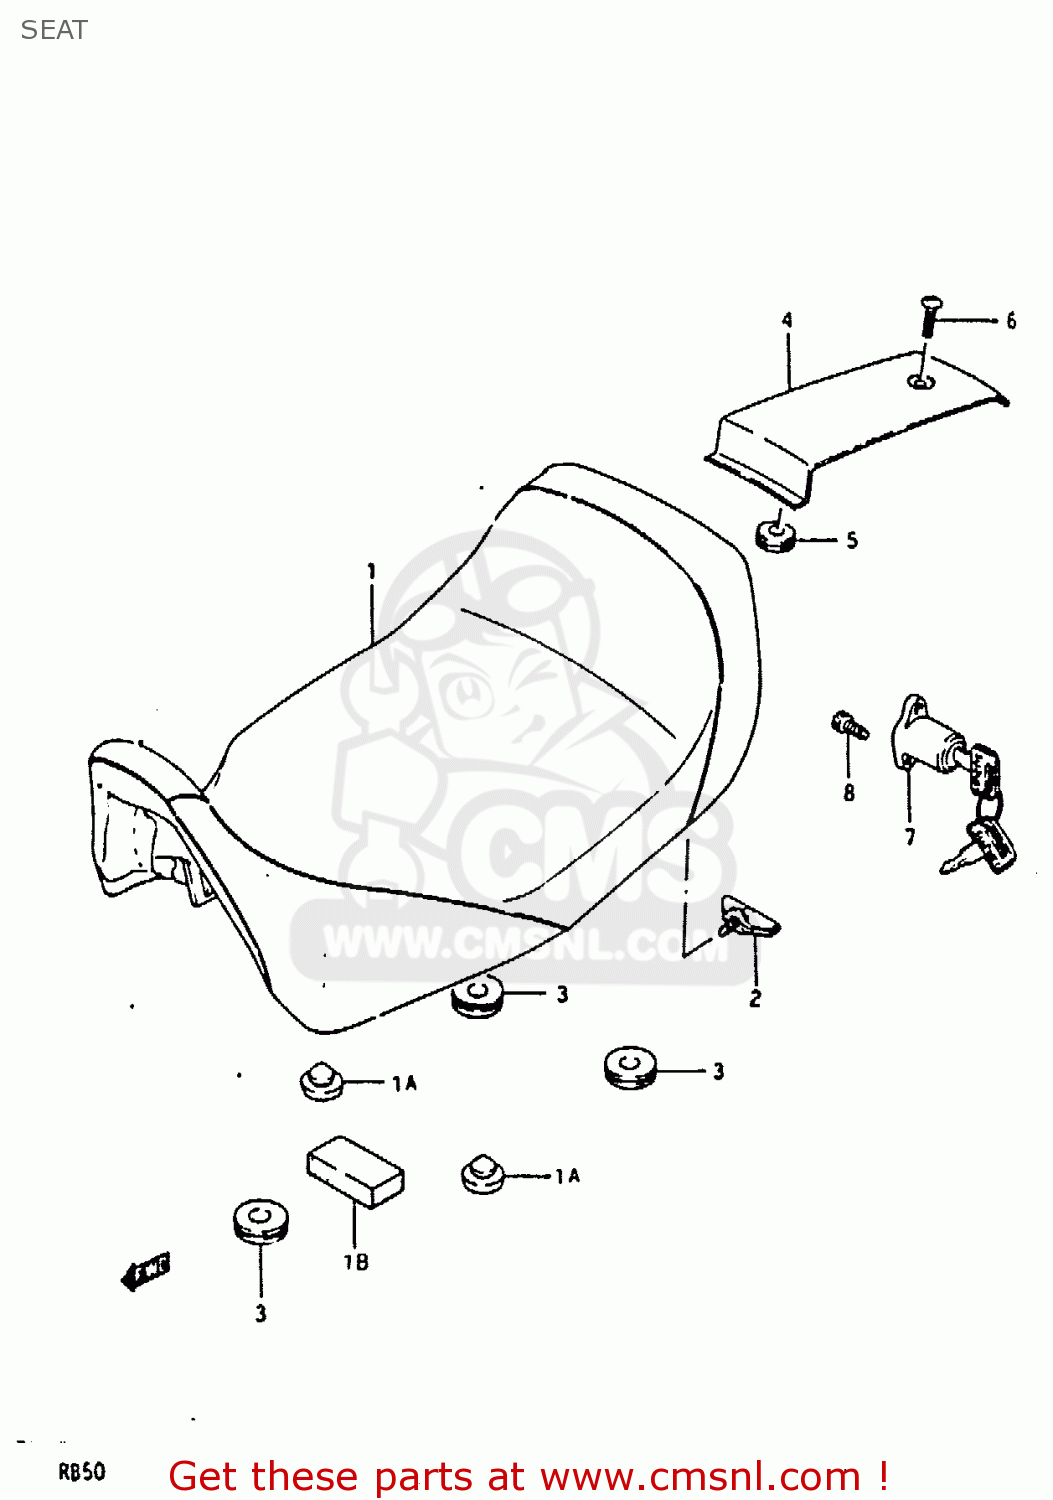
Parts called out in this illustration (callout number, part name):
1	SEAT SET
1A	CUSHION
1B	CUSHION,BATTERY STOPPER
2	BOLT
3	CUSHION
4	KAP.DUOZIT
5	CUSHION
6	SCREW (L:20)
7	LOCK SET
8	BOLT
